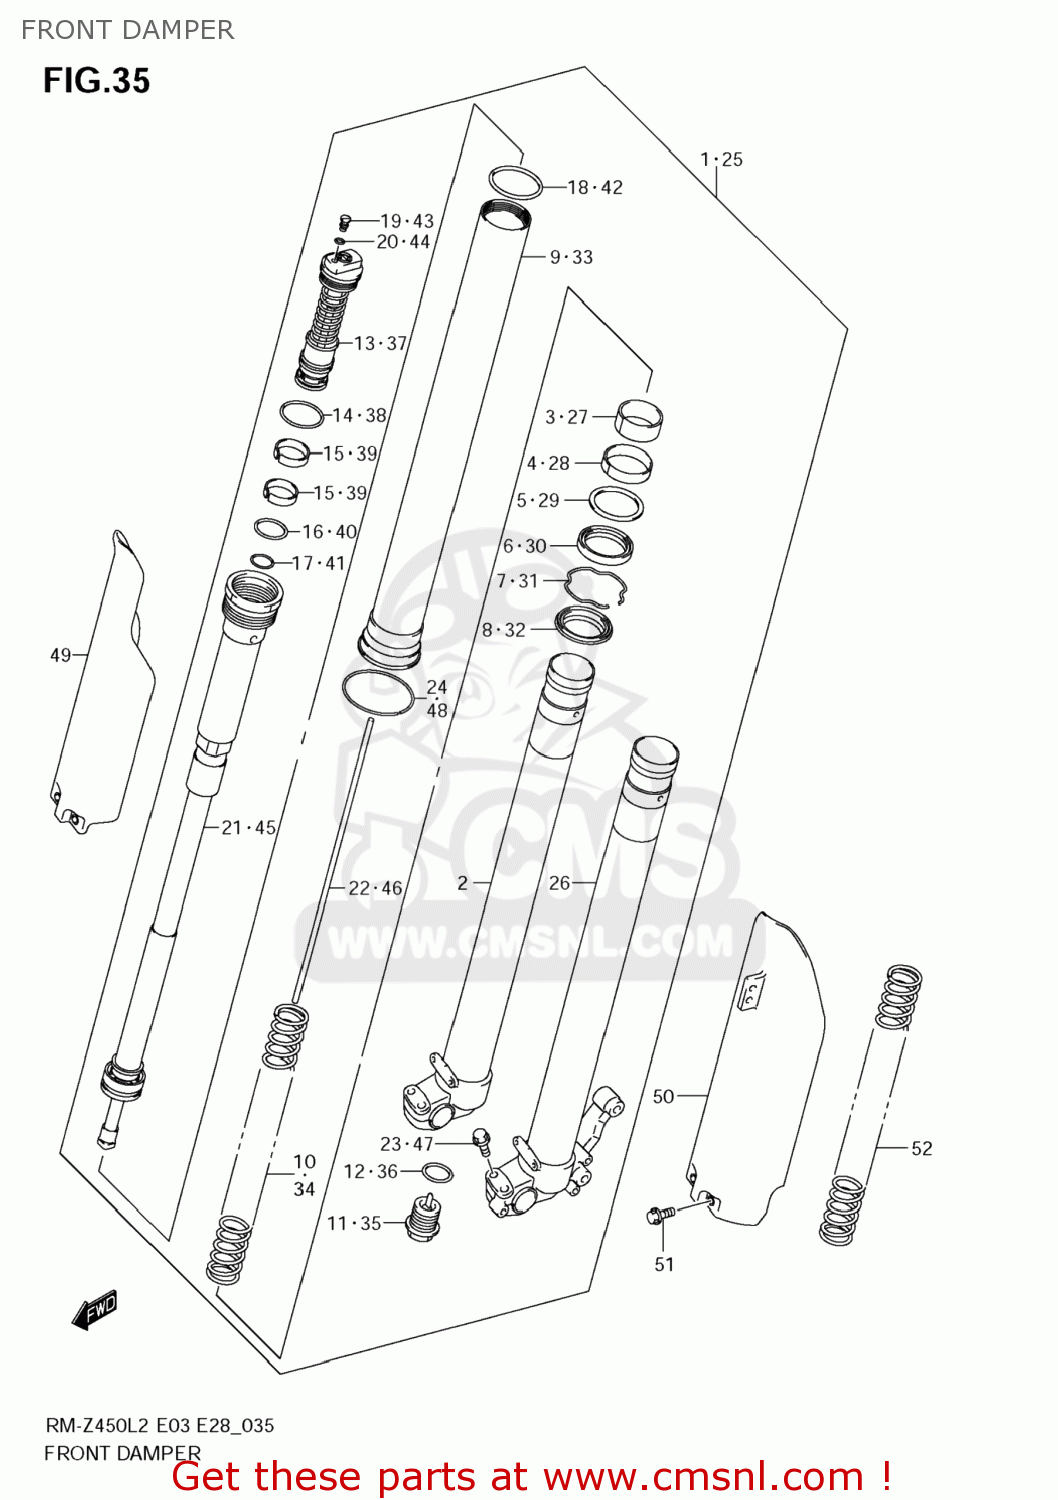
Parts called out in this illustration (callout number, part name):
1	DAMPER ASSY,FR FORK,R
2	TUBE,INNER,R
3	BUSH
4	BUSH,GUIDE
5	SPACER,SEAL
6	SEAL,OIL
7	RING,OIL SEAL STOPPER
8	SEAL,DUST
9	TUBE,OUTER
10	SPRING,FR(K=0.48)
11	BOLT,CTR
12	O RING
13	BOLT,FORK
14	O RING
15	BUSH
16	O RING
17	O RING
18	O RING
19	BOLT,PLUG
20	O RING,PLUG
21	ROD,DAMPER
22	ROD,PUSH
23	BOLT
24	STOPPER,RING
25	DAMPER ASSY,FR FORK,L
26	TUBE,INNER,L
27	BUSH
28	BUSH,GUIDE
29	SPACER,SEAL
30	SEAL,OIL
31	RING,OIL SEAL STOPPER
32	SEAL,DUST
33	TUBE,OUTER
34	SPRING,FR(K=0.48)
35	BOLT,CTR
36	O RING
37	BOLT,FORK
38	O RING
39	BUSH
40	O RING
41	O RING
42	O RING
43	BOLT,PLUG
44	O RING,PLUG
45	ROD,DAMPER
46	ROD,PUSH
47	BOLT
48	STOPPER,RING
49	PROTECTOR,FRON
50	PROTECTOR,FRON
51	BOLT(6X10)
52	SPRING,FR(K=0.5)
